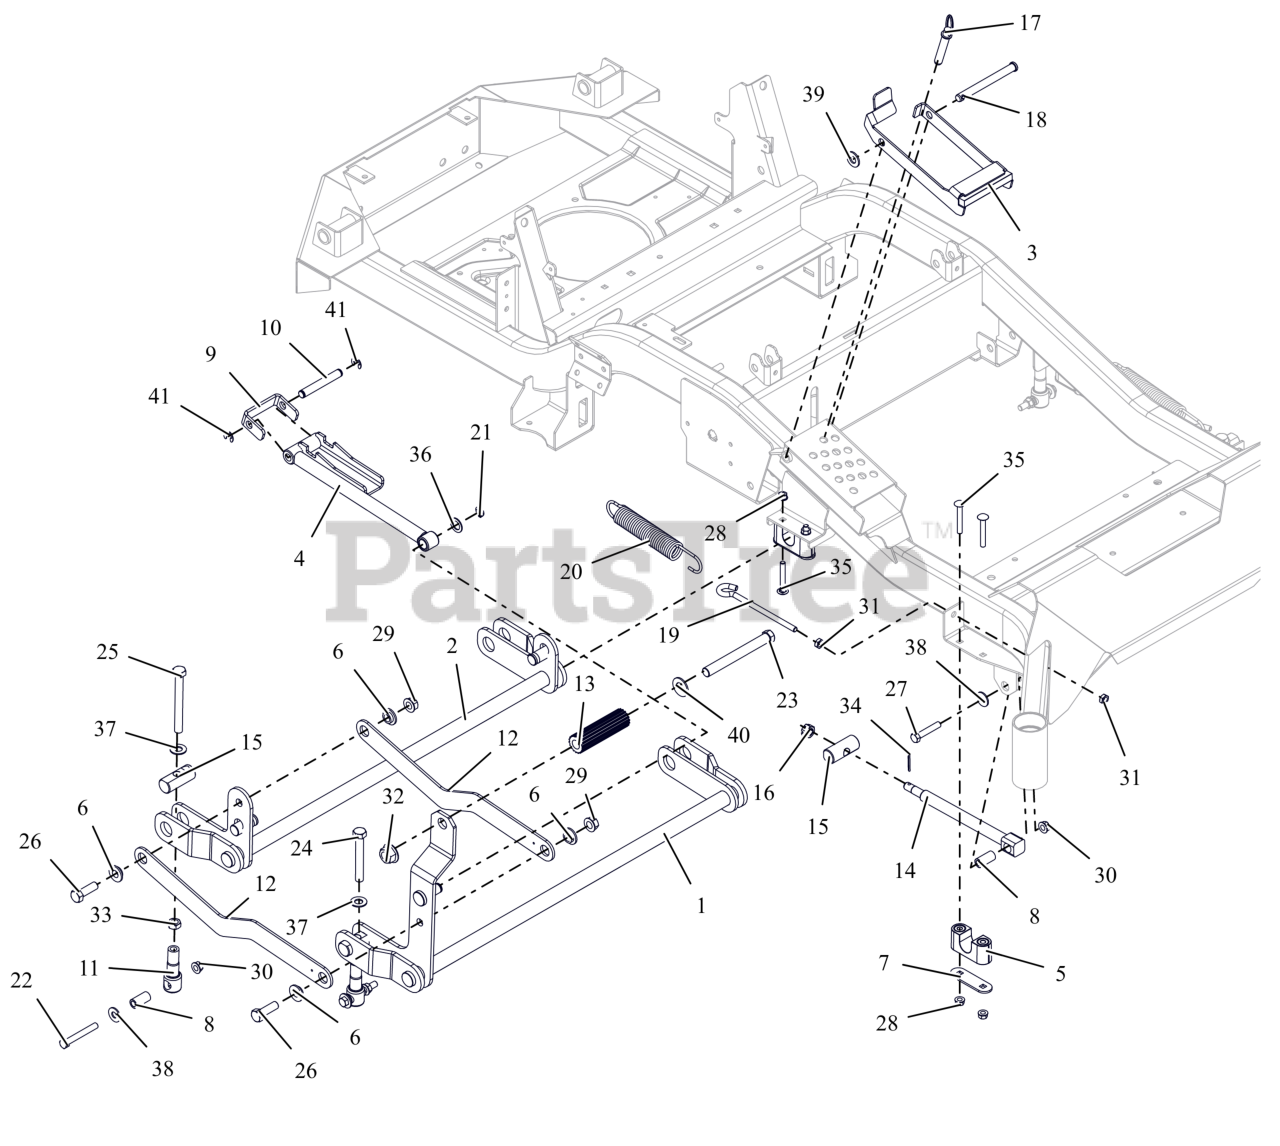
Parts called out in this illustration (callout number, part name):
1	WLDMT, FRONT DECK LIFT PIVOT
2	WLDMT, REAR DECK LIFT PIVOT
3	BRKT, HOC TRANSFER LOCK
4	WLDMT, HOC ARM
5	ASM-BUSHING, DECK LIFT
6	BSHG-FLG .515X.750X.395X1.120
7	PLATE, BEARING SUPPORT
8	SPACER, DECK LEVELING
9	BRKT, HOC LINE
10	ROD, HOC PIVOT
11	LINK, DECK LIFT FORMED
12	LINK, DECK LIFT
13	ROD, FOOT PEDAL (BLACK)
14	DRAG,LINK-HD
15	PIN, DECK LIFT
16	NUT-SL .50-13
17	PIN, .50 X 2.20 USABLE LG BALL
18	PIN-SLIC .50X4.97X4.55 -ZCC
19	BOLT,.38-16 X 5.25-.62 DIA EYE
20	SG-TENS .162X1.25X8.25 WLD 25
21	RG-RTNG-EXT .625X.050
22	BLT, HEX .38-16X2.75 G8 ZCC
23	BLT, HEX .62-11X5.50 G5 FBP
24	BLT, HEX .50-13X3.50F G5 ZCC
25	BLT, HEX .50-13X4.50F G8 ZCC
26	BLT,HEX .50-13X1.50 G5 ZCC
27	BLT,HEX .38-16X2.00 G5 ZCC
28	NUT,LK-CTR-FLG .31-18 GF ZCC
29	NUT-LK-TOP-FLG .500-13 GF ZCC
30	NUT-LK-TOP-FLG .38-16 ZC120
31	NUT-JAM .375-16 G2 ZCC
32	NUT,FLG-TOP LK .625-11 FBP
33	NUT-JAM .500-13 G2 ZCC
34	PIN,CTR.12X1.25EXTPRSQCT ZC120
35	BLT, RHSSN.31-18X2.25 G5 ZCC
36	WSHR, FLT .630X1.005X.062 ZCC
37	WSHR, FLT .557X1.040X.102 ZCC
38	WSHR,FLT .438X1.00X.083 ZCC
39	WSHR,FLT .531X1.062X.095 ZCC
40	WSHRFLT 5/8SAE CARBHARD FBP
41	RG-RTNG-EXT .500X.042 (E)
